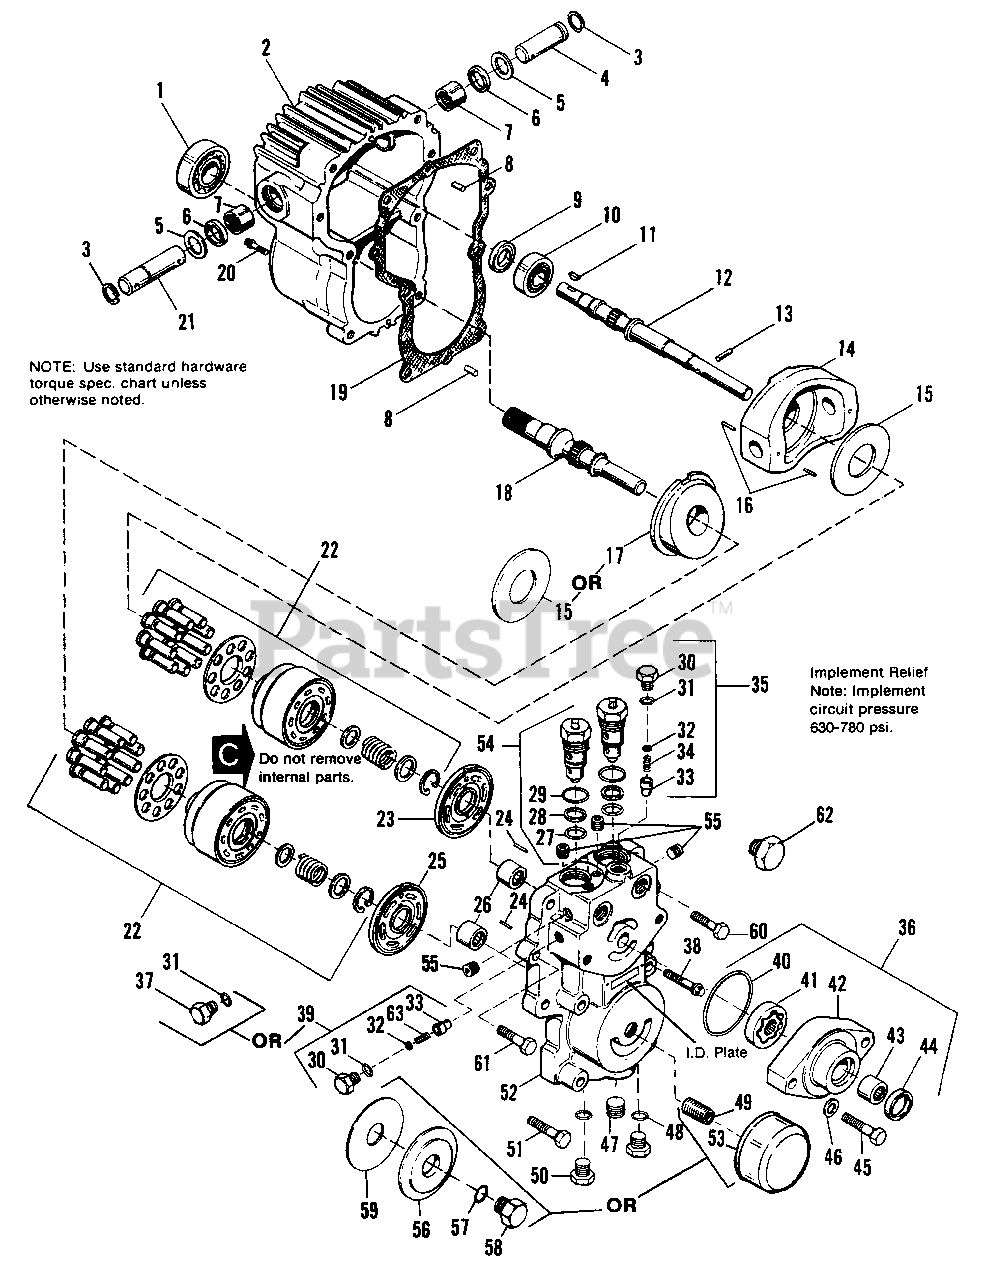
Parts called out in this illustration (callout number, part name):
1	Bearing, Ball (1079,1204,1240,1241,1224,1230)
2	Housing (1079,1204,1240,1241)
2	Housing (1224,1230)
3	Ring, Retainer (1079,1204,1240,1241,1224,1230)
4	Trunnion (1079,1204,1240,1241,1224,1230)
5	Washer, Special (1079,1204,1240,1241,1224,1230)
6	Seal, Lip (1079,1204,1240,1241,1224,1230)
7	Bearing, Needle (1079,1204,1240,1241,1224,1230)
8	Pin, Headless, Straight (1079,1204,1240,1241,1224,1230)
9	Seal, Lip (1079,1204,1240,1241,1224,1230)
10	Bearing, Ball (1079,1204,1240,1241,1224,1230)
11	Key, Woodruff (1079,1204,1240,1241,1224,1230)
12	Shaft, Pump (1079,1204,1240,1241,1224,1230)
13	Pin Headless (1079,1204,1240,1241,1224,1230)
14	Plate, Swash (1079,1204,1240,1241)
14	Plate, Swash (1224,1230)
15	Plate, Swash (1079,1204,1240,1241)
15	Plate, Thrust (1224,1230)
16	Pin, Spring, Coiled (1079,1204,1240,1241,1224,1230)
17	Plate, Swash (1079,1204,1240,1241)
18	Shaft Motor (1079,1204,1240,1241,1224,1230)
19	Gasket (1079,1204,1240,1241,1224,1230)
20	Capscrew, 12 pt. (1079,1204,1240,1241)
21	Trunnion (1079,1204,1240,1241,1224,1230)
22	Cylinder Block Kit (1079,1204,1240,1241)
22	Cylinder Block Kit (1224,1230)
23	Plate, Valve (1079,1204,1240,1241,1224,1230)
24	Pin, Straight (1079,1204,1240,1241,1224,1230)
25	Plate Valve (1079,1204,1240,1241,1224,1230)
26	Bearing, Needle (1079,1204,1240,1241,1224,1230)
27	O-Ring (1079,1204,1240,1241,1224,1230)
28	Ring Backup (1079,1204,1240,1241,1224,1230)
29	O-RING
30	Plug, Hex Hd.(1204,1241,1230)
31	O-Ring (1079,1204,1240,1241,1224,1230)
32	Shim (1079,1204,1240,1241,1224,1230)
33	Cone, Relief Valve (1079,1204,1240,1241,1224,1230)
34	Spring, Relief Valve (1079,1240,1224)
34	Spring, Relief Valve (1204,1241,1230)
35	Relief Valve Kit (1079,1240,1224)
35	Relief Valve Kit (1204,1241,1230)
36	Charge Pump Kit (1079,1204,1240,1241,1224,1230)
37	Plug, Hex Hd. (1079,1240,1224,)
38	Capscrew, 12 pt. (1079,1204,1240,1241,1224,1230)
39	Charge Relief Valve (1204,1241,1230)
40	O-Ring (1079,1204,1240,1241,1224,1230)
43	Bearing, Needle (1079,1204,1240,1241,1224,1230)
44	Seal, Lip (1079,1204,1240,1241,1224,1230)
45	Capscrew, 7/16-14 x 2 (1079,1204,1240,1241,1224,1230)
46	Washer, Flat (1079,1204,1240,1241,1224,1230)
47	Plug, Pipe (1240,1241,1224,1230)
48	O-Ring (1079,1204,1240,1241,1224,1230)
49	Union, Filter (1240,1241,1224,1230)
50	Plug, Hex Hd. (1079,1204,1240,1241,1224,1230)
51	Capscrew, 3/8-16 x 2 (1079,1204,1240,1241,1224,1230)
52	Section, Center (1079,1204,1240,1241,1224,1230)
53	Filter (Short canister) (1240,1241,1224,1230)
54	Check Valve (1079,1204,1240,1241,1224,1230)
54	Check Valve (1224,1230)
55	Plug, Pipe (1079,1204,1240,1241,1224,1230)
56	Plate, Cover (1079,1204)
57	O-Ring (1079,1204)
58	Plug, Special (1079,1204)
59	Gasket (1079,1204)
60	Capscrew, 3/8-16 x 1-1/2 (1079,1204,1240,1241)
61	Capscrew, 3/8-16 x 1-1/4 (1079,1204,1224,1230)
62	Plug, Hex Hd. (1079,1240,1224)
63	Spring, Relief Valve (1204,1241,1230)
